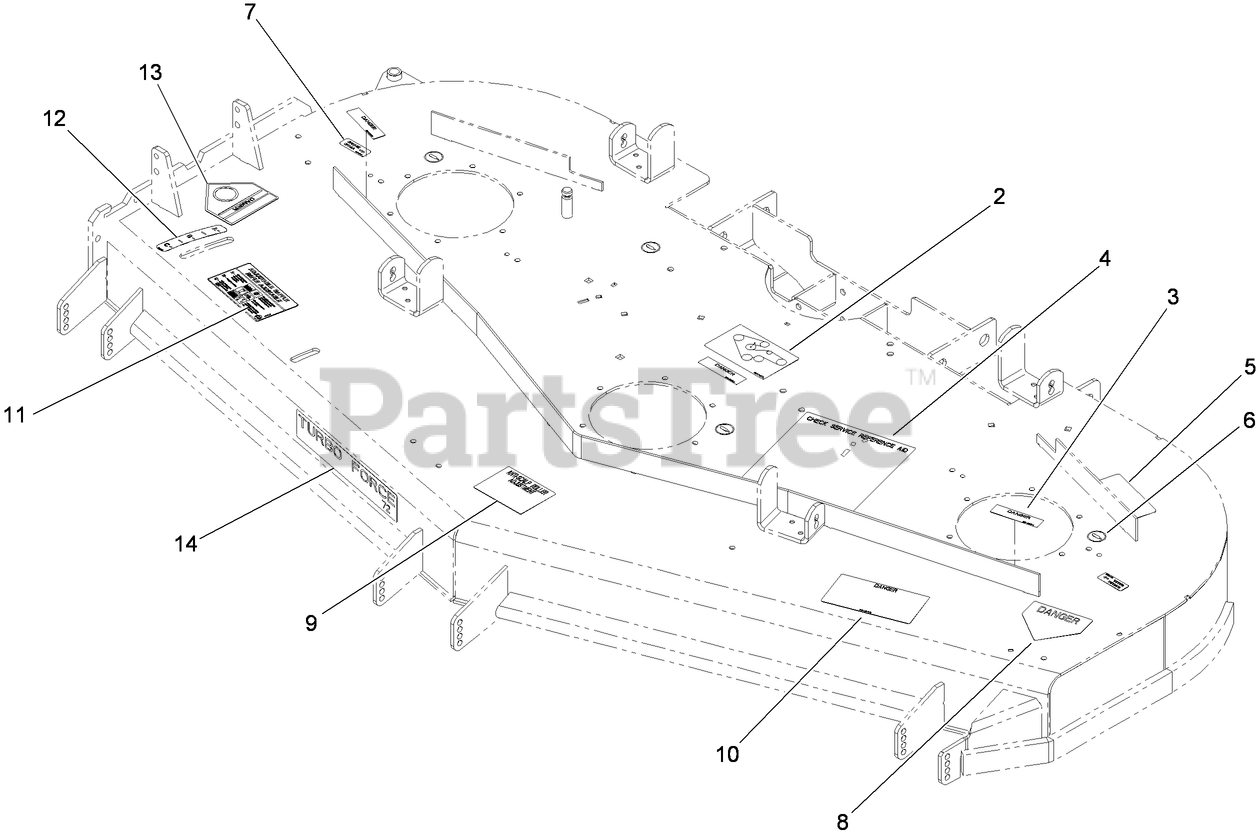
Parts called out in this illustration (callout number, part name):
2	DECAL-ROUTING, BELT
3	DECAL-COVER, MISSING
4	DECAL-CHECK, SERVICE
5	DECAL-TORQUE
6	DECAL-GREASE
7	Decal-Grease
8	DECAL-DANGER
9	DECAL-SCALP, ANTI
10	DECAL-DANGER, THROWN OBJECT
11	DECAL-ADJUSTMENT, BAFFLE
12	DECAL-SETTING, BAFFLE
13	DECAL-DANGER
